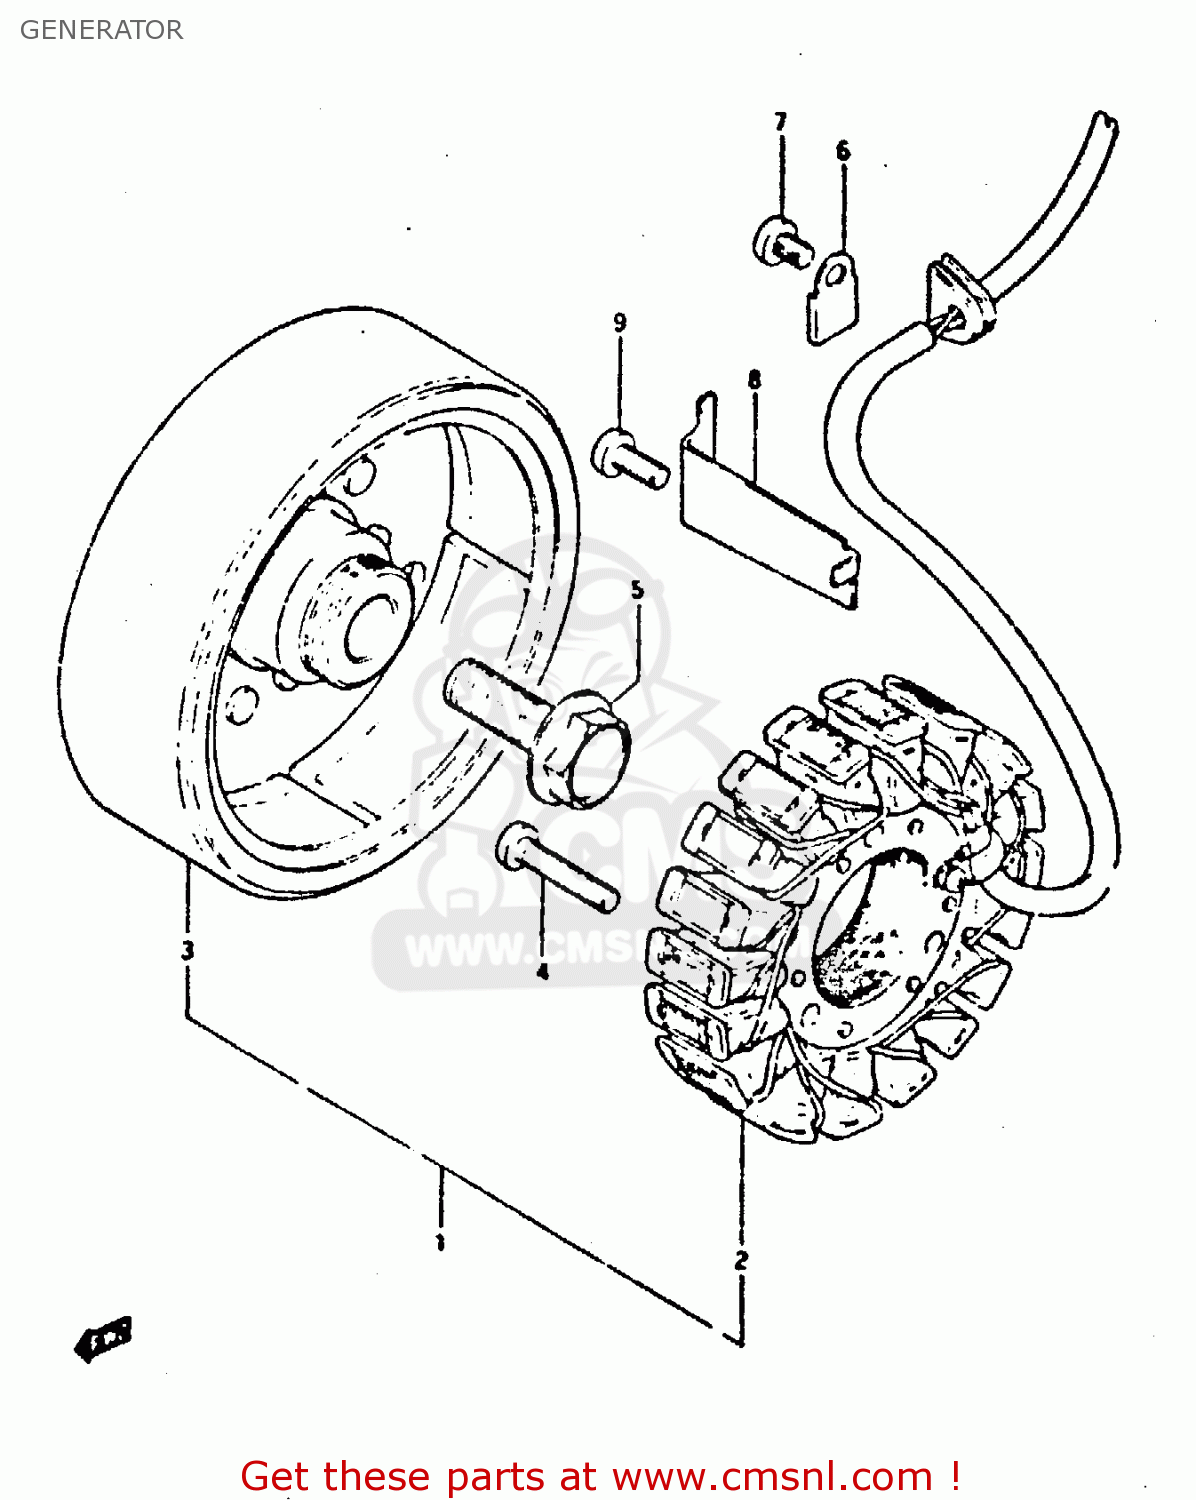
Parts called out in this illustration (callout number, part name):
1	ALTERNATOR ASSEMBLY
2	STARTER ASSY
3	ROTOR ASSEMBLY
4	SCREW 6X30
5	BOLT(14X43)
6	CLAMP,GENERATOR LEAD WIRE
7	SCREW
8	CLAMP,GENERATOR LEAD WIRE
9	SCREW
